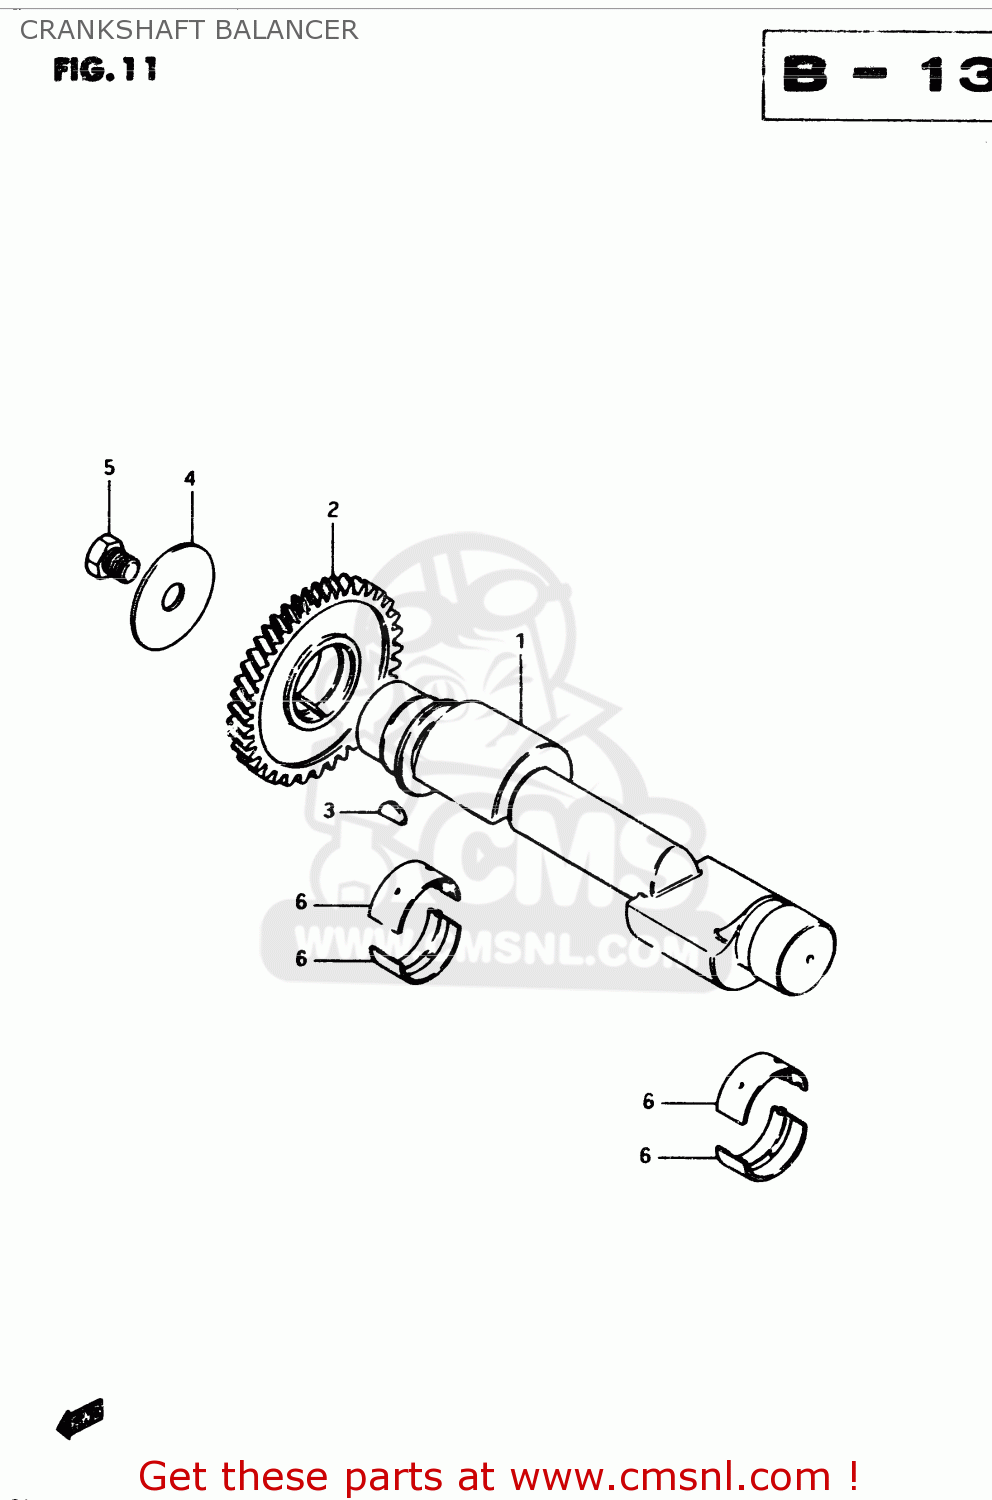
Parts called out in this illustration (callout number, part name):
1	BALANCER,CRANKSHAFT
2	GEAR,CRANK BALANCER
3	KEY 4MM
4	WASHER(12X50X3)
5	BOLT
6	METAL CRANKSHAFT (BROWN)
